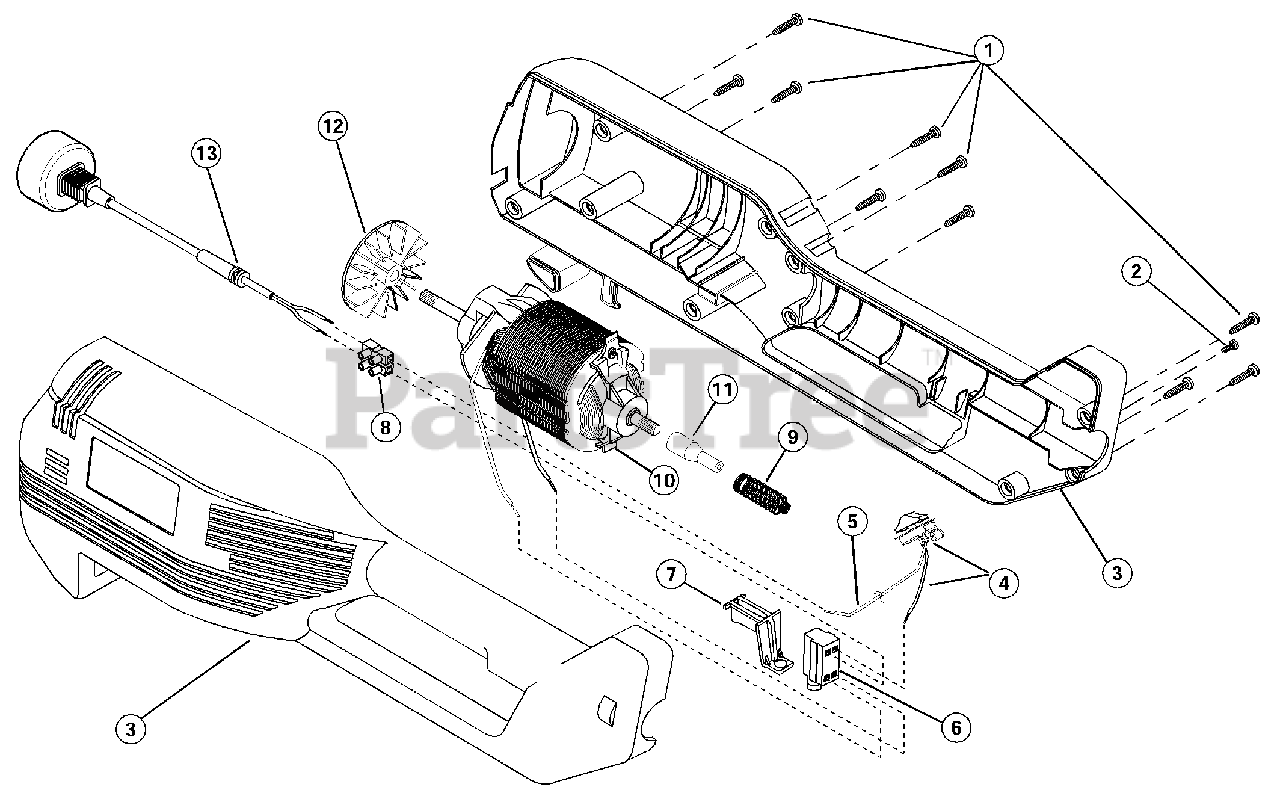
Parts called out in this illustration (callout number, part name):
1	Housing Screw
2	Anti-Rotation Screw
3	Motor Housing Assembly
4	Two-Speed Switch Assembly
5	Lead Wires
7	Trigger
8	Terminal Block
10	Motor Assembly
12	Cooling Fan
13	Power Cord Assembly
